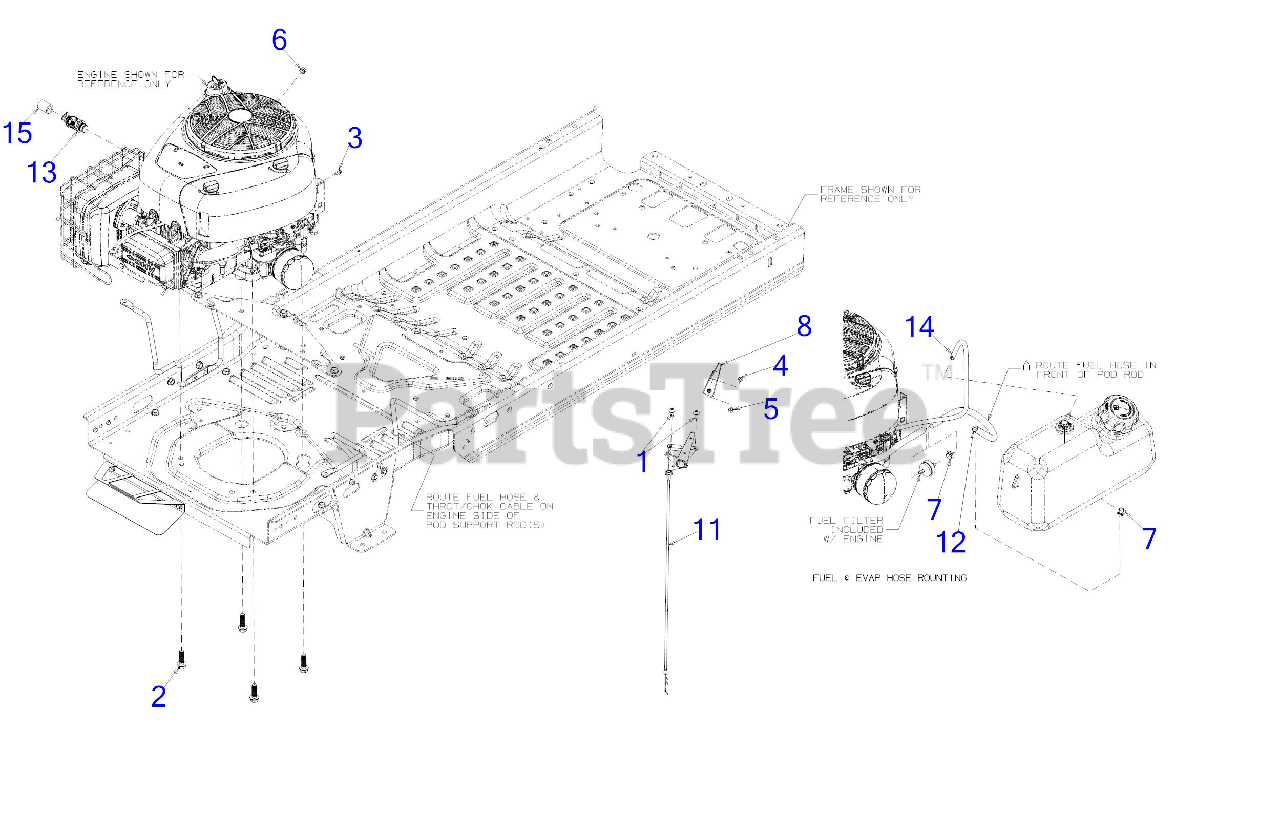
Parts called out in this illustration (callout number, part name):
1	SCREW 1/4-20 x .5
2	SCREW 3/8-16 X1.250
3	SCREW #12-24 x .375
4	SCREW #8-32X.38 LG
5	HEX NUT 8-32
6	SEMS NUT 1/4-20
7	HOSE CLAMP 1/20
8	THROTTLE CONTROL KNOB
11	THROTTLE/CHOKE CABLE
12	FUEL HOSE LOW PERMEATION
13	OIL DRAIN VALVE
14	VENT HOSE 3/16 ID
15	DRAIN HOSE 14''
